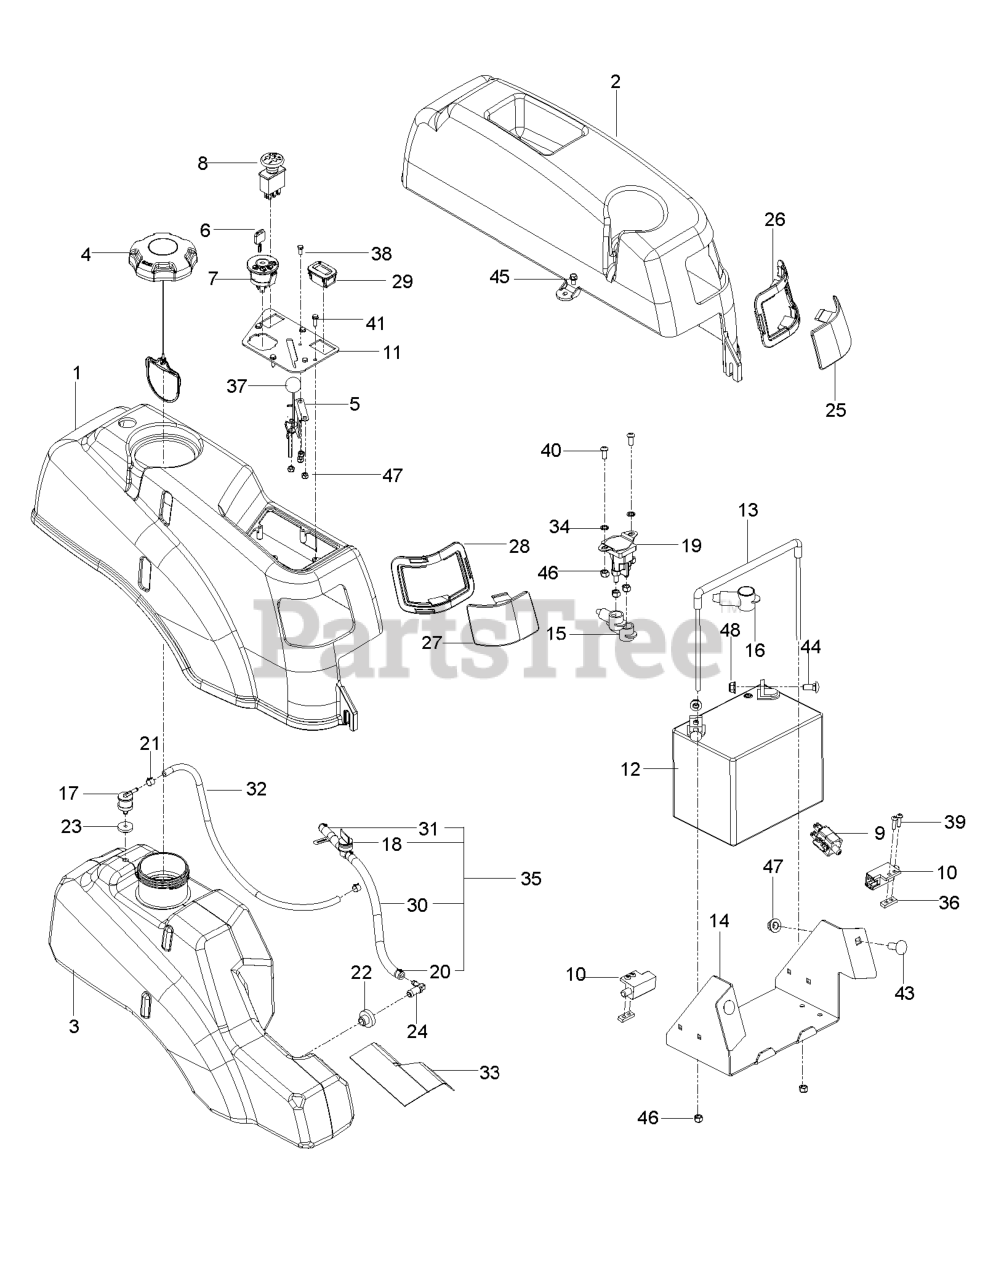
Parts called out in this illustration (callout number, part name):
1	FENDER RT, GRAY
2	FENDER, LT
3	TANK.FUEL.RT.EPA
4	CAP, FUEL
5	CABLE, THROTTLE
6	KEY
7	RP IGNITION SWITCH
8	SWITCH.PTO
9	SWITCH, BRAKE 3P
10	SWITCH INTERLOCKT
11	CONSOLE.PLATE
12	BATTERY, 12 V 330 AMP
13	BATTERY TIE DOWN ASSEMBLY
14	BOX, BATTERY, BLACK
15	TERMINAL COVER-SM
17	VALVE.FUEL.CHECK
18	FUEL VALVE
20	HOSE CLAMP
21	CLAMP, HOSE
22	RUBBER GROMMET
23	GROMMET, CHECK VALVE
24	STEM, FUEL TANK
26	RING, TRIM LT BLK
27	PANEL, RT, BLK
28	RING, TRIM, RT-BLK
29	HOUR METER
30	GAS LINE 10"
31	FUEL LINE 3"
32	HOSE, FUEL, 3/16" X 17-1/4"
33	SHIELD, HEAT
34	WASHER 1/4 INT TOOTH
35	FUEL LINE ASSY
36	TAPPED PLATE
37	KNOB.ROUND.BALL.BLACK
38	HCS #10-24 X 1/2
39	SCR #10-24 X .75 SKT HD BLK
40	SCR 1/4-20 X 5/8 BTN SKT HD ZD
41	SCR #10-12X3/4 HEX WAS HD ZD
43	RHSNB 3/8C X 1
44	BOLT 5/16C X 3/4" CARRIAGE
45	BOLT 1/4-20 X 1/2 HWST
46	NUT.1/4-20.HEX.NYLOC.ZD
47	NUT 10-24 NYLOC
48	5/16-18 NYLOC FLANGE NUT
